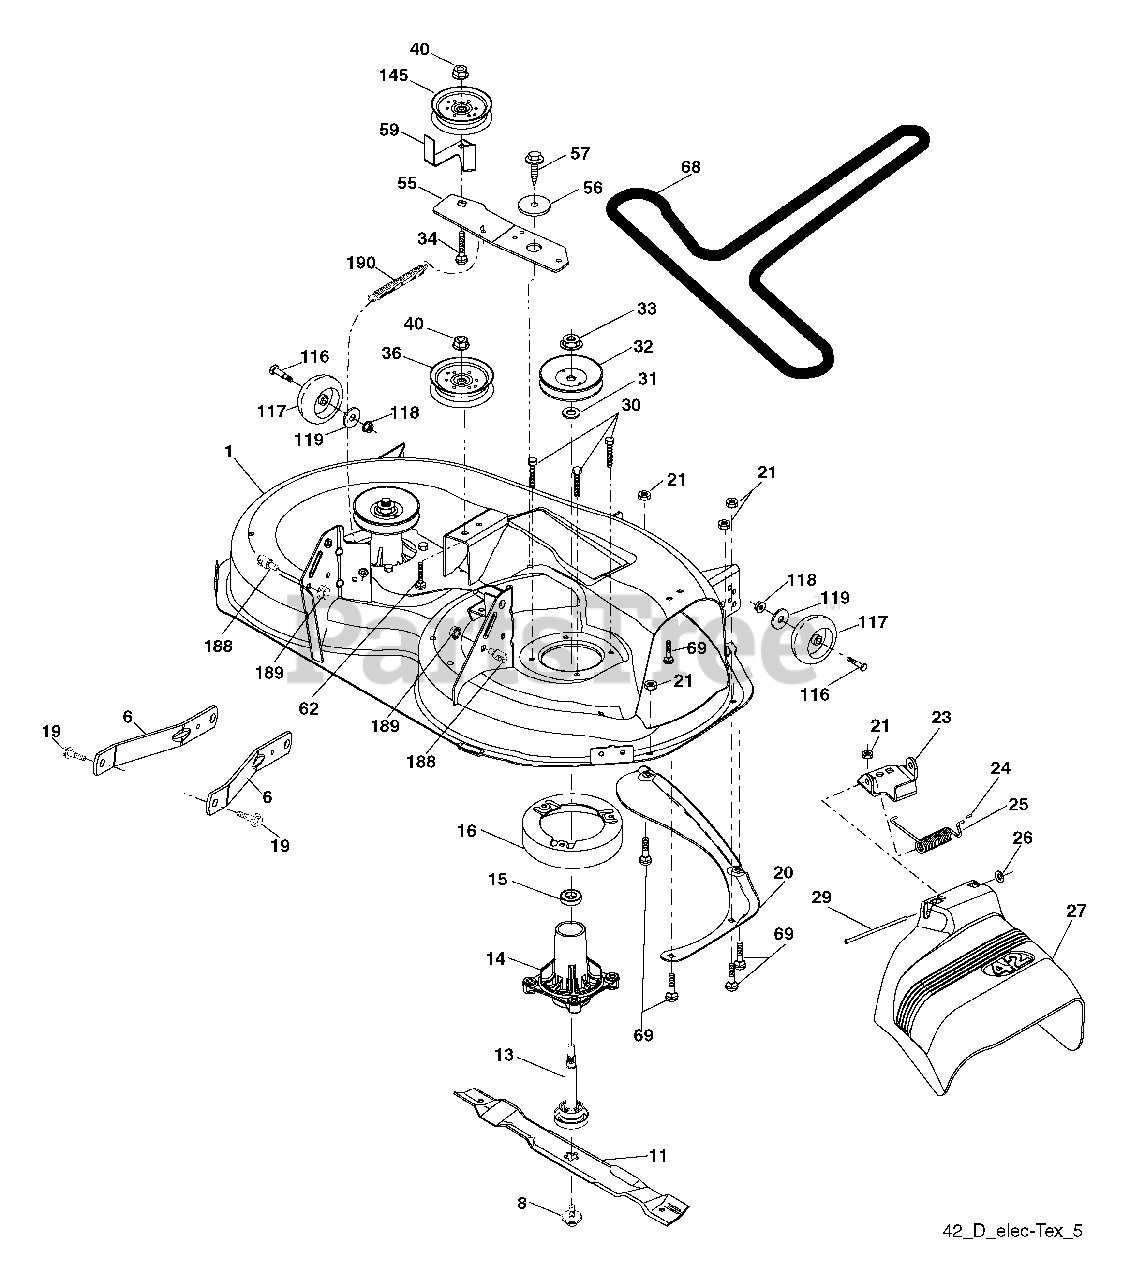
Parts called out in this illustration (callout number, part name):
1	Mower Housing
6	Arm Suspension
8	Bolt/Washer asm 7/16-20 unf
11	Blade, 42" Mulching Premium
11	Blade, 42" Hi-Lift
11	Blade, 42" Mulching Std
13	Shaft Assembly, Mandrel
14	Housing, Mandrel
15	Bearing, Ball, Mandrel
16	Stripper, Mower Deck
19	Bolt, Shoulder
20	Baffle, Vortex
21	Nut, Crownlock 5/16-18 unc
23	Bracket, Deflector
24	Cap, Sleeve
25	Spring, Torsion, Deflector
27	Shield, Deflector
29	Rod, Hinge
30	Screw Thdrol Rolling Wsh Hd
31	Washer, Spacer
32	Pulley, Mandrel
33	Nut, Toplock, Flanged
34	Bolt Carr Sh. 3/8-16 x 1-1/2 Gr. 5
36	Pulley, Idler, Flat
40	Nut, Lock Flg. 3/8-16 unc
55	Arm, Idler
56	Spacer, Retainer
57	Screw 3/8-16 x 1
59	Guard, Tuv Idler
62	Bolt 3/8-16 unc x 2
69	Bolt 5/16-18 x 5/8
116	Bolt, Shoulder
117	Wheel, Gauge
118	Nut, Crownlock 3/8-1
119	Washer 13/32 x 7/8 x 14 Ga.
145	Pulley Idler
188	Stud Fastener
189	Nut Lock Hex Flange
190	Spring Mower Drive
